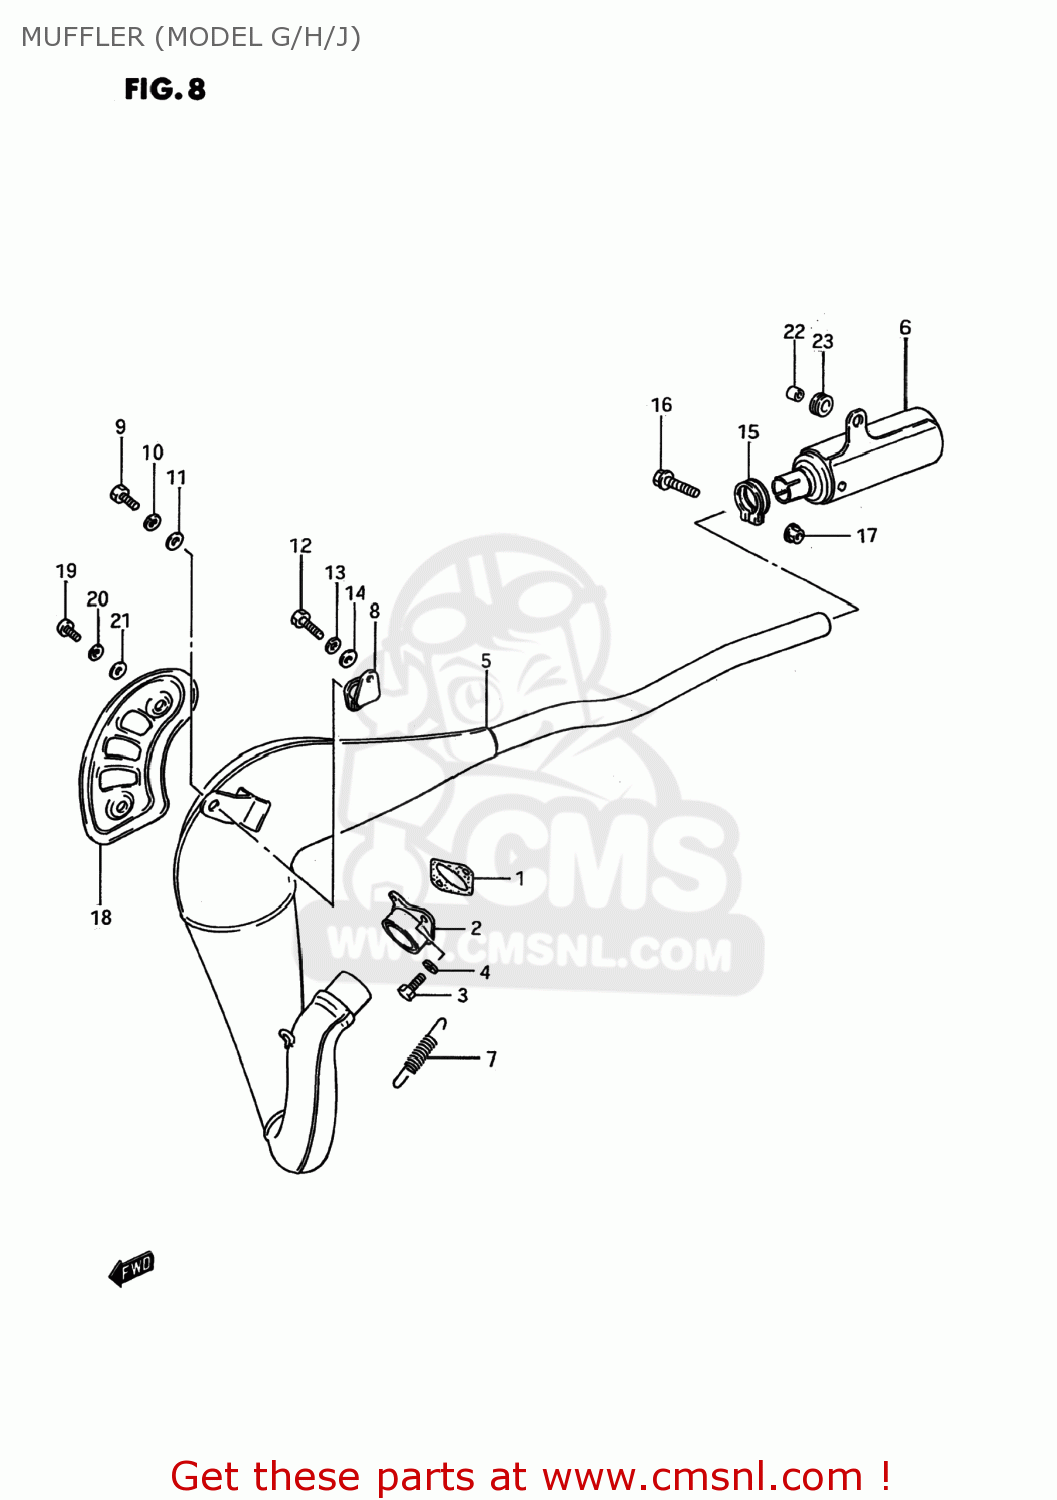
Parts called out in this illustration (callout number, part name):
1	GASKET,EXHAUST FLANGE (NAS)
2	FLANGE,EXHAUST PIPE
3	BOLT
4	WASHER,LOCK
5	BODY,MUFFLER
6	BODY,MUFFLER
7	SPRING
8	DAMPER,MUFFLER SUPPORT
9	BOLT
10	WASHER,LOCK
11	WASHER
12	BOLT 6X16
13	WASHER,LOCK
14	WASHER
15	CLAMP
16	BOLT 6X25
17	NUT 6MM
18	COVER,MUFFLER
19	SCREW
20	WASHER,LOCK
21	WASHER
22	SPACER
23	CUSHION
